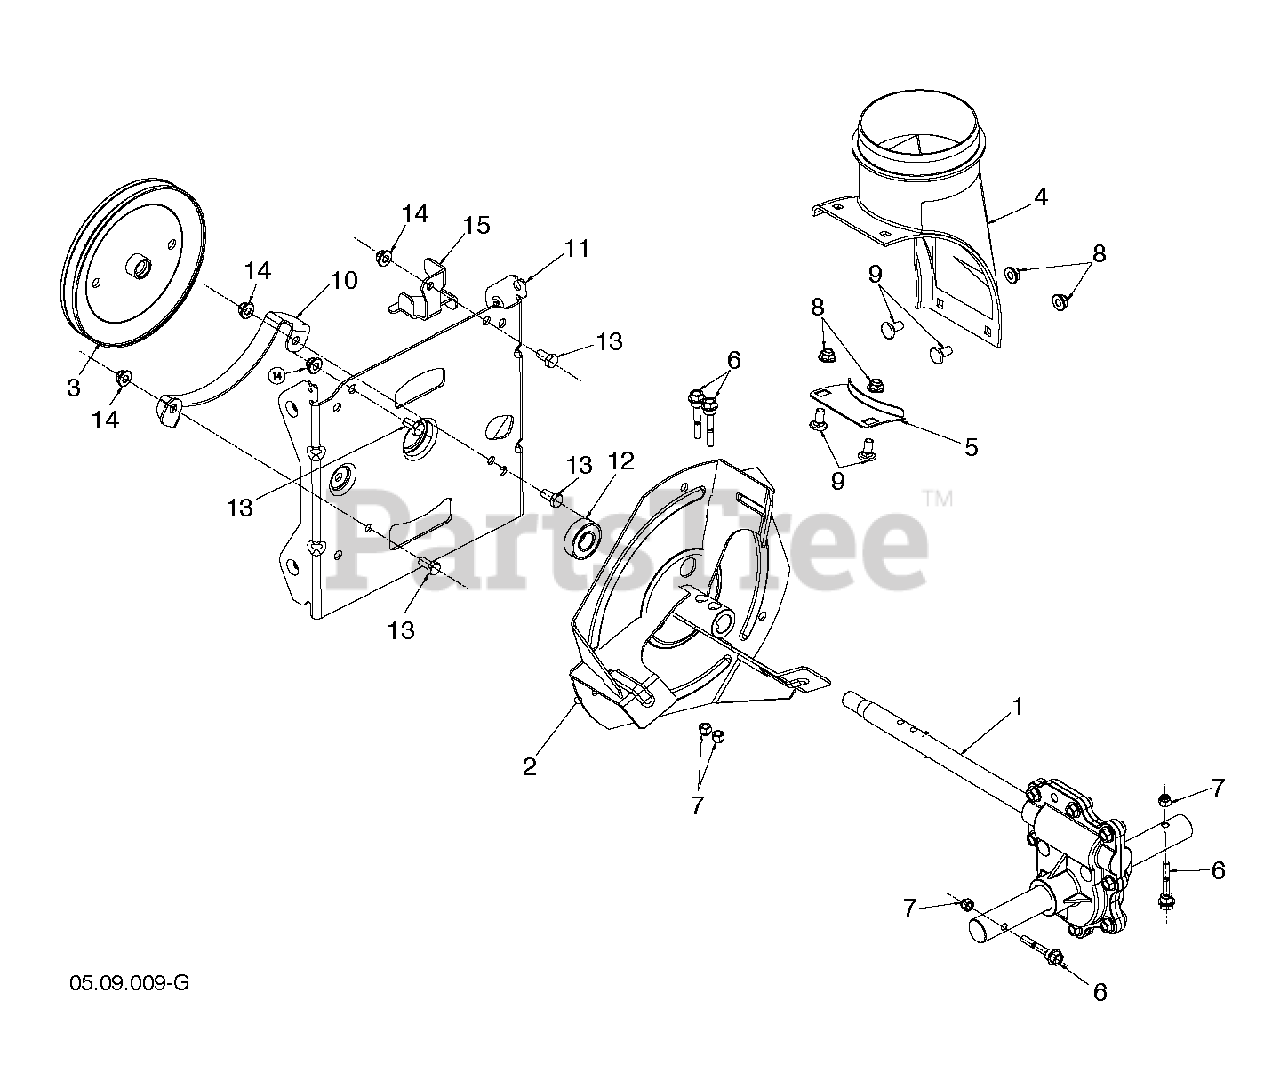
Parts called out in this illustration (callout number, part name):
1	GEARBOX.AUGER.
2	Impeller, Steel Snow Black
3	Screw-on Pulley, 7.3 5/8
4	Discharge Chute Base
5	BRACKET, CORNER DISCHARGE
6	Hex Head Shear Bolt, 1/4-20 X 1-13/16
7	LOCKNUT.NYLOC.1/4-20
8	Flange Hex Nut, Nylock Blk 5.16-1
9	Carriage Wafer Bolt, 5/16-18
10	BRACKET.BELT.KEEPER.LOWER.BLAC
11	Auger Housing Inter Bracket, Black
13	BOLT, HEX HEAD 5/16-18
14	NUTNYLOK.FLRANGE.5/16-18
15	Auger Belt Guide, Lower 479
